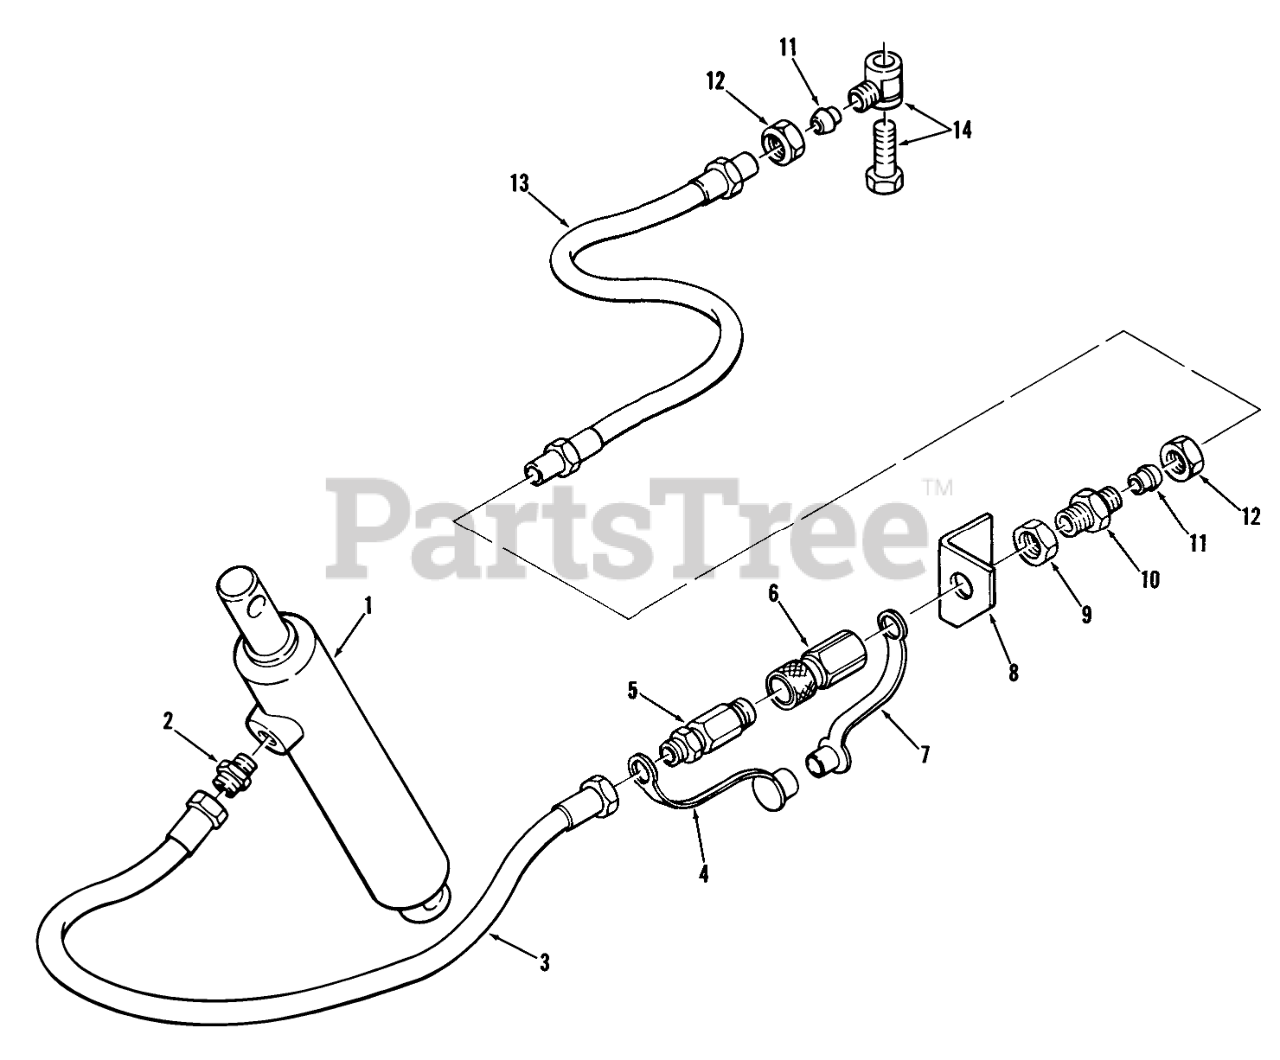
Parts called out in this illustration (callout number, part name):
1	Hydraulic Cylinder
2	FITTING
3	Hydraulic Hose
4	DUST CAP
5	Coupling Plug
6	Q.D. Fitting
7	Dust Cap
8	Mounting Plate
10	Fitting
11	RING SEAL
14	JOINT (CONSISTS 2 PT
20	Bolt
46	Lock Nut 5/16-18
54	Decal
55	Decal
